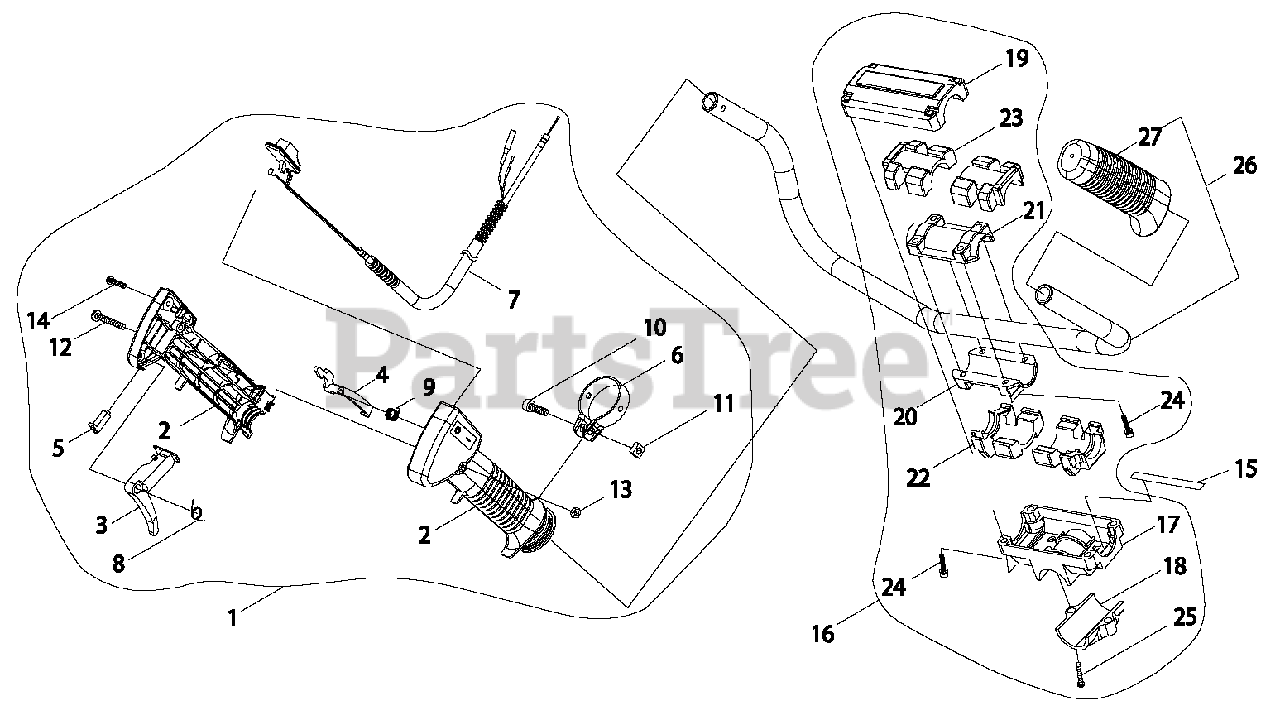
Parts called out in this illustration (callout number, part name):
1	THROTTLE CONTROL ASSY
2	GRIP BODY SET
3	TRIGGER, THROTTLE
4	LOCKOUT, THROTTLE
5	BUTTON
6	CLAMP
7	CABLE ASSY, CONTROL
8	SPRING, RETURN
9	SPRING
10	BOLT 6×20
11	NUT
12	SCREW M5×35
13	NUT - 5
14	SCREW, TAPPING
15	LEAD - GROUND
16	BRACKET KIT, HANDLEBAR
17	BRACKET, LOWER
18	BRACKET, MOUNTING
19	BRACKET, UPPER
20	CLAMP, LOWER
21	CLAMP, UPPER
22	CUSHION, LOWER
23	CUSHION, UPPER
24	BOLT M5×25
25	SCREW M6×25
26	HANDLEBAR ASSY
27	GRIP
